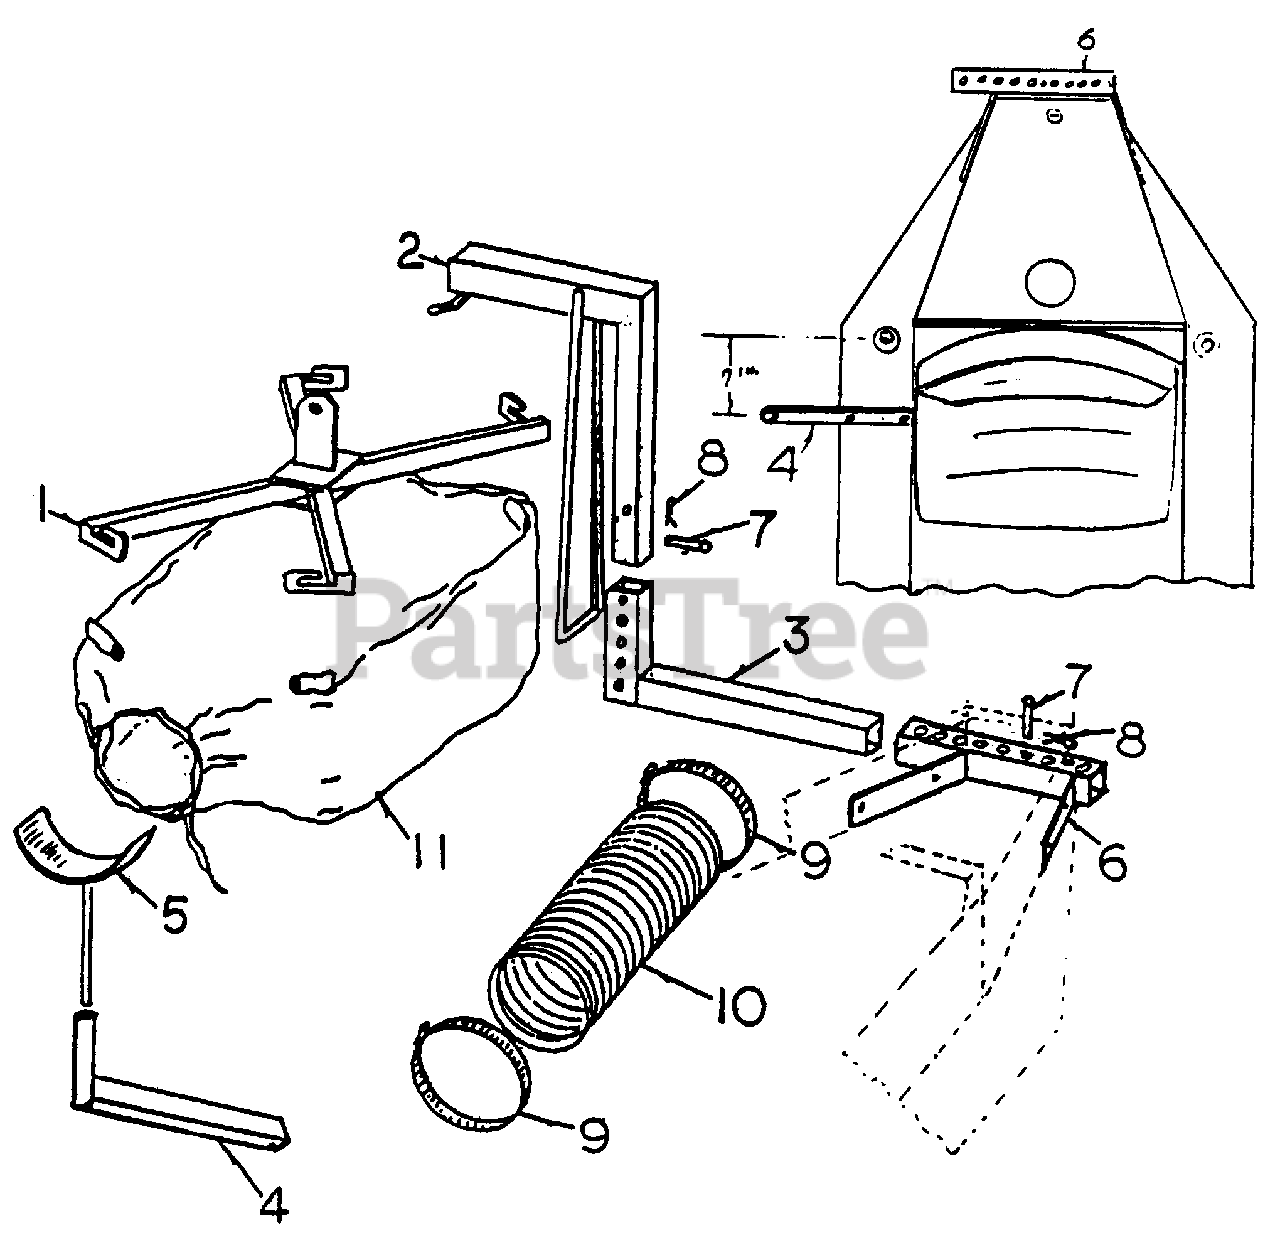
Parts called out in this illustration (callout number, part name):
1	GRASS BAG HANGER
2	VERTICAL ARM
3	HORIZONTAL ARM
4	HANGER BRACKET
5	VAC HOSE SADDLE
6	REAR MOUNTING BRACKET
7	PINS
10	HOSE
11	BAG
